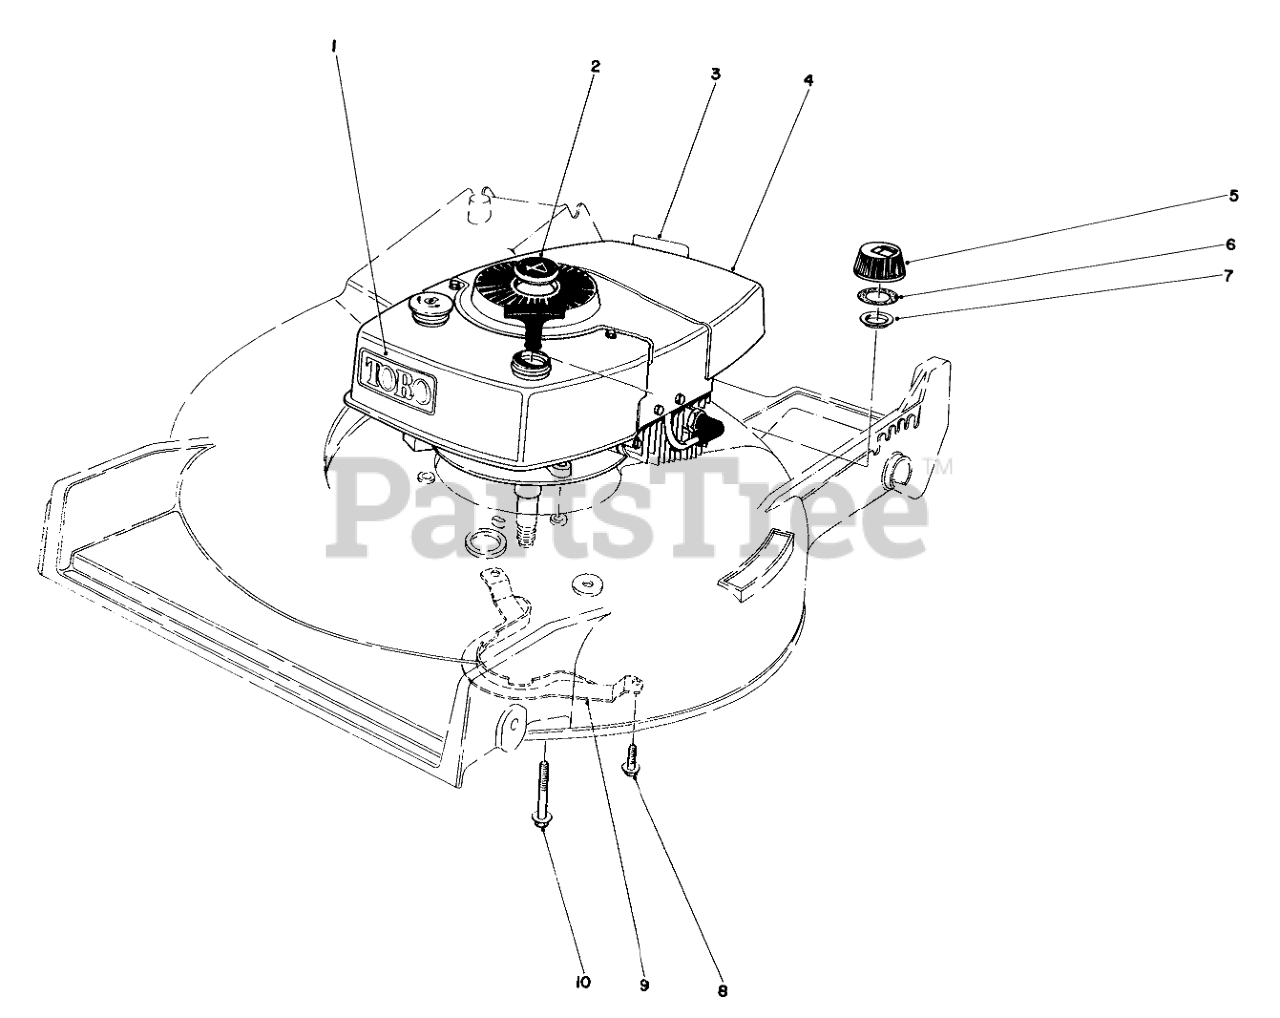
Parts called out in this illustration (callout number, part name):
1	Decal Tow
2	PLUG BUTTON
3	Decal-Maintenan
4	Engine
5	Gas Cap Assembly (Incl. Ref. #6 & 7)
6	GASKET
7	GAS CAP BAFFLE
8	Screw
9	BELT GUIDE
10	3/8-16 X 2 CAPSCREW
